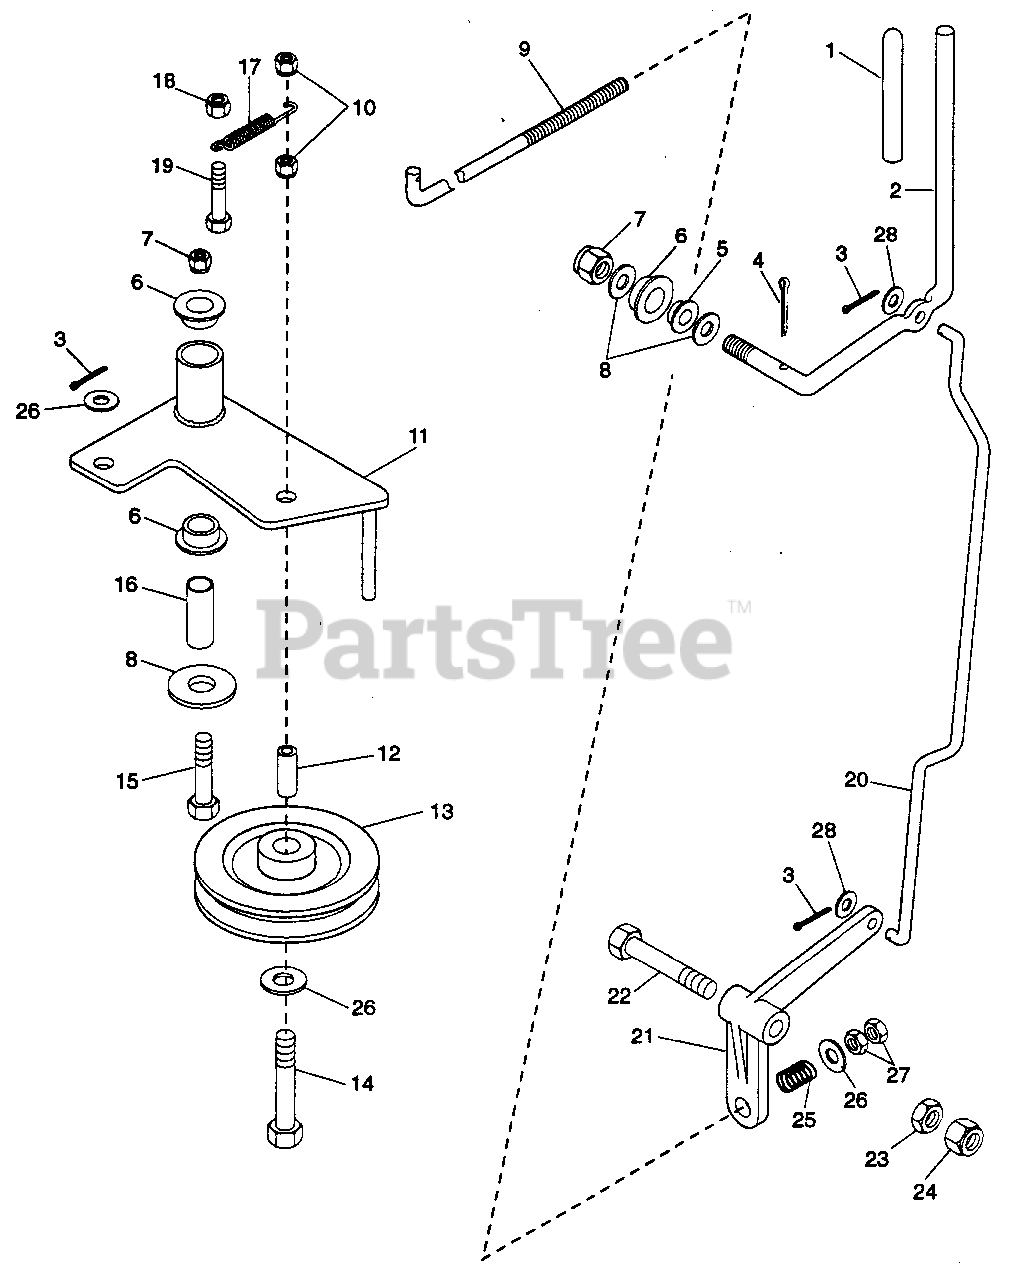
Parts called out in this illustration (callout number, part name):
1	GRIP, PTO LEVER
2	LVR, PTO ACTUATING
3	PIN-COTR .09 X .75 PL
4	PIN-COTR .188 X 1.625
5	BUSH., F .515 X 1.00 X .745 NY
6	BSHG-FLG .762 X 1.0 X .580 X 1.48 NY
7	NUT-LK-NYL .50-13 PL
8	WSHR-FL-STL .531 X 1.250 X .100
9	PTO LINK ROD, PRO-150
10	NUT-LK-NYL .375-16 PL
11	DECLUTCH ARM-PRO PTO
12	SPACER .391 ID X .62 OD X 1.0
13	IDLER - PLY
14	BLT-HEX .38-16 X 3.50 PL GR 5
15	BLT-HEX .50-13 X 3.50 PL GR 5
16	BUSHING FOR DECLUTCH ARM PIVOT
17	SG-TENS .095 X .85 X 4.38 WLD 25
18	NUT-LK-NYL .312-18 PL
19	BLT-HEX .31-18 X 1.25 PL GR 5
20	PTO LEVER LINK ROD, PRO 150
21	LVR, PTO CLUTCH
22	BLT-HEX .50-13 X 2.50 PL GR 5
23	NUT .50-13 PL
24	NUT-LK .50-13 HEX TYPE N
25	SG-COMP .125 X .78 X 1.00
26	WSHR-FL-STL .406 X .812 X .065 PL
27	NUT-HEX .375-16
28	WSHR-FL-STL .344 X .688 X .065 PL
